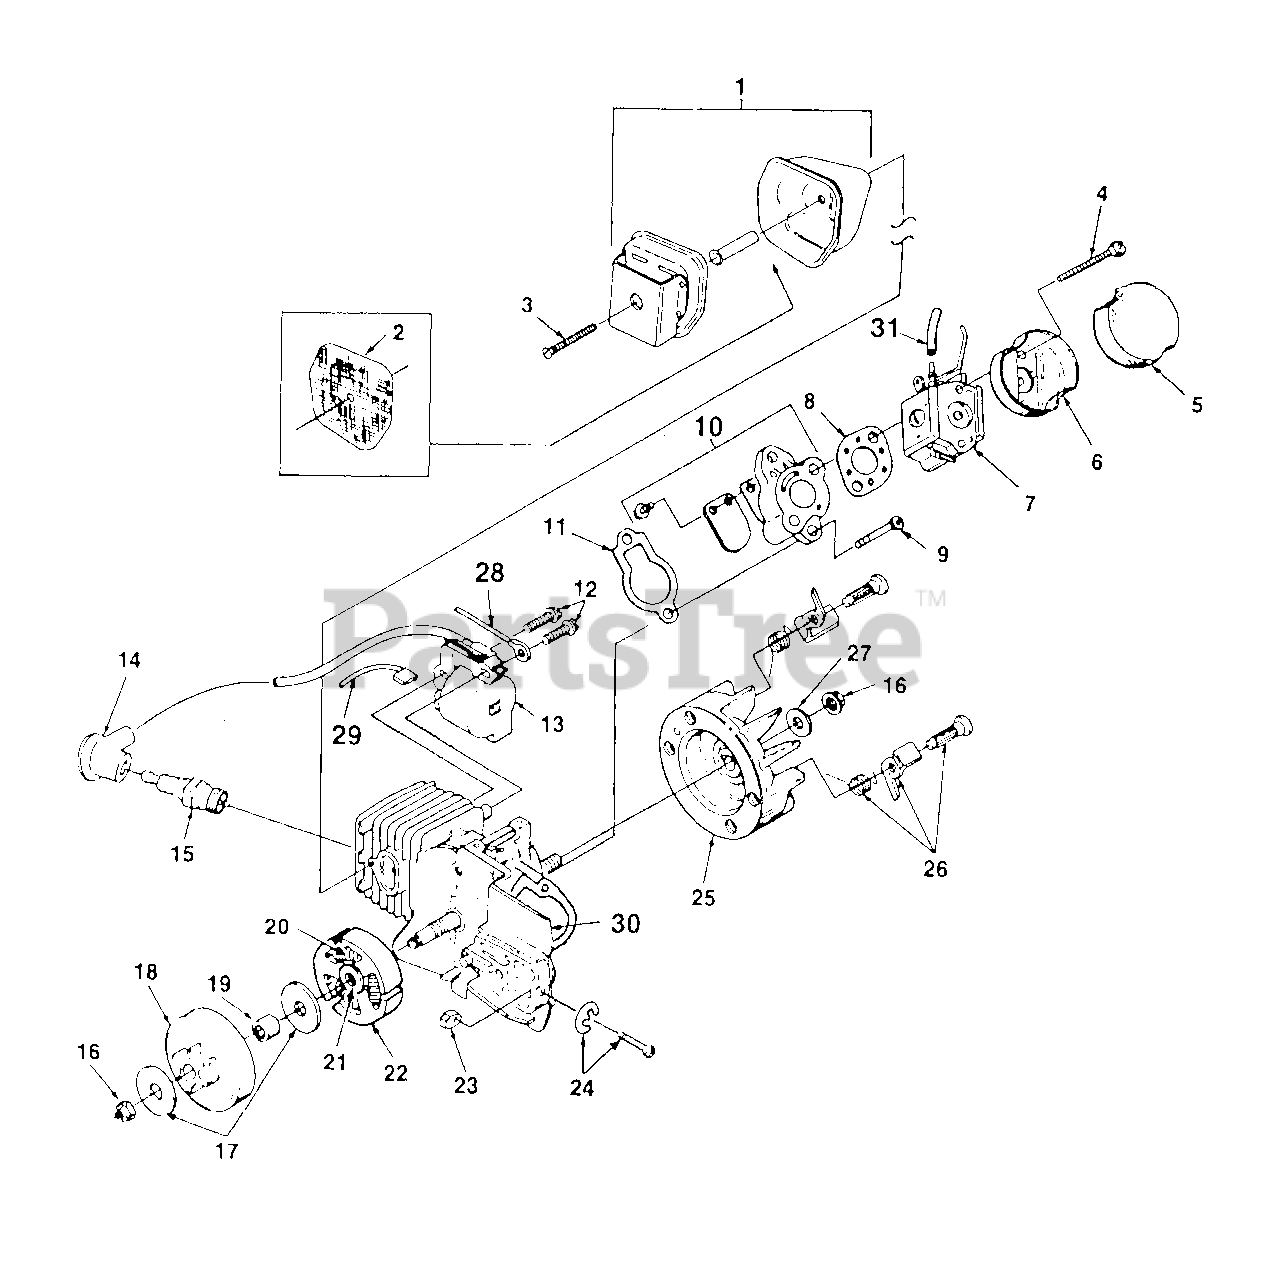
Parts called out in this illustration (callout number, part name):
1	MUFFLER-Complete
2	SCREEN-Spark Arrestor
3	SCREW-Sems (10-24 X 1 7/8")
4	SCREW-Thd. Form. (#8 X 1.65)
5	FILTER-Air
6	CUP-Filter
7	CARBURETOR
8	GASKET-Carburetor
9	SCREW-Plastite (#10 X 7/8")
10	HEAT DAM & REED
11	GASKET-Heat Dam
12	SCREW-Taptite (8-32 X 1")
13	MODULE-ignition
14	TERMINAL
15	SPARK PLUG
16	NUT-(5/16-24)
17	WASHER-Thrust
18	SPROCKET & DRUM
19	BEARING
20	SPRING-Clutch
21	SPIDER-Clutch
22	SHOE-Clutch
23	PIN-Adjusting
24	SCREW & E RING KIT
25	ROTOR & STARTER PAWLS
26	STARTER PAWL KIT
27	WASHER-(5/16")
28	LEAD-Ring Term.
29	LEAD-Double Flag
30	SHORT BLOCK
31	TUBING- Rubber (2 1/4")
